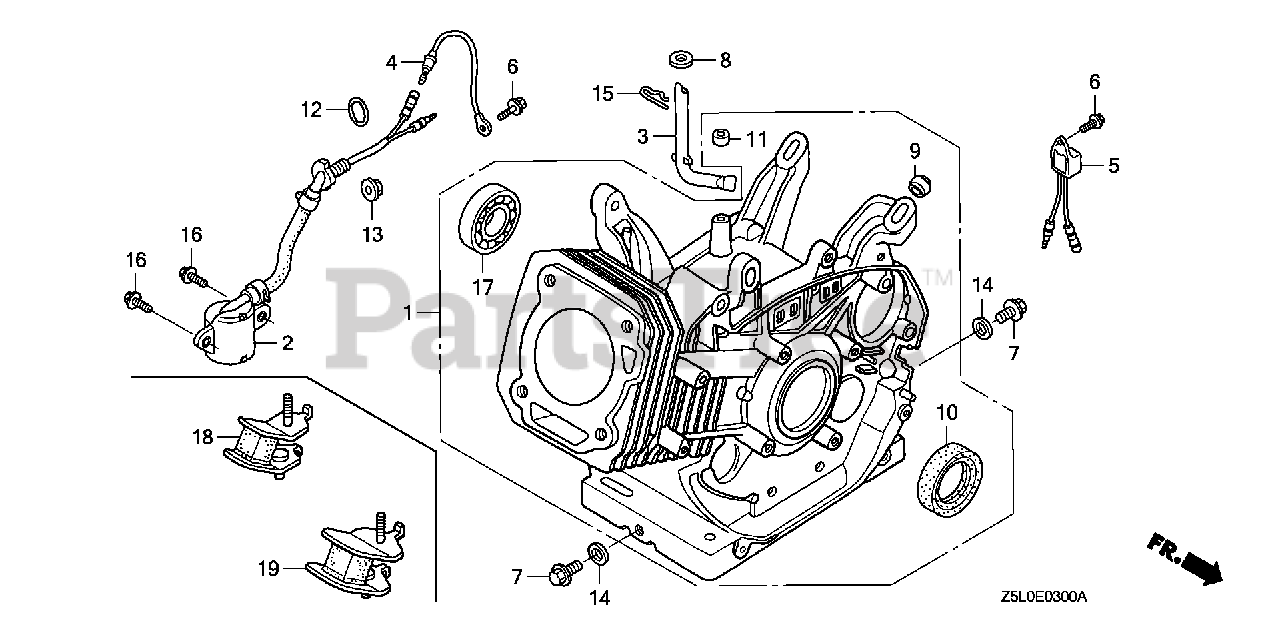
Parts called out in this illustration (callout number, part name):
1	CYLINDER ASSY. (SELF STARTER+ALERT)
2	SWITCH ASSY., OIL LEVEL
3	SHAFT, GOVERNOR ARM
7	BOLT, DRAIN PLUG (12X15)
8	WASHER (8.2X17X0.8)
10	OIL SEAL (35X52X8)
11	OIL SEAL (8X14X5)
12	O-RING (13.5X1.5) (ARAI)
12	O-RING (14MM) (NOK)
13	NUT, FLANGE (10MM)
14	WASHER, DRAIN PLUG (12MM)
15	PIN, LOCK (10MM)
16	BOLT, FLANGE (6X12)
17	BEARING, RADIAL BALL (6202)
